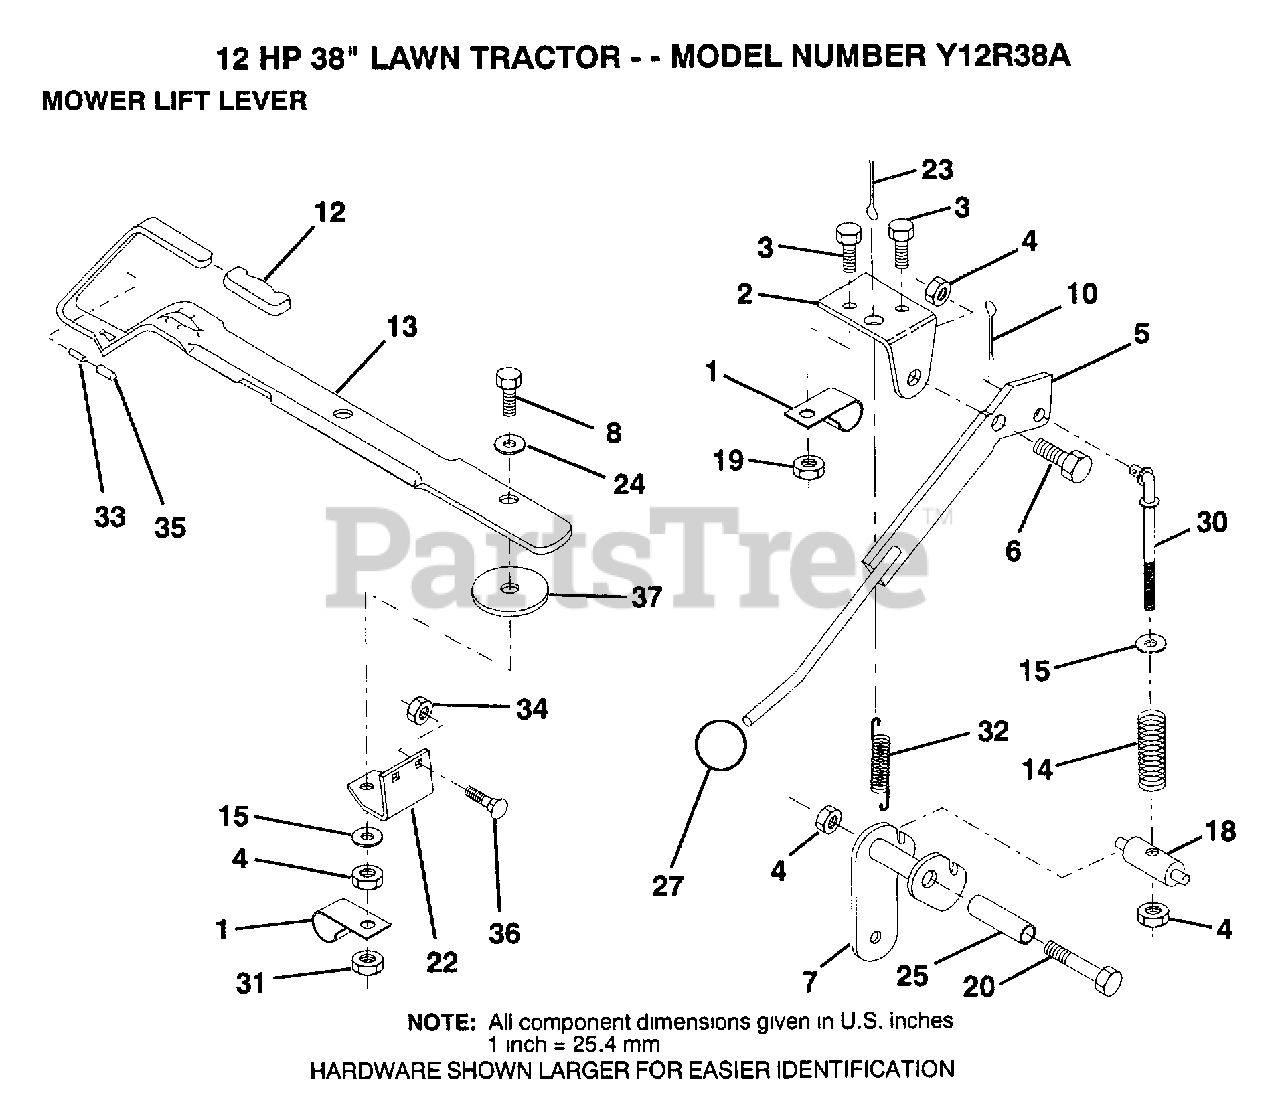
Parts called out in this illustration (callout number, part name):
1	"CLIP,INSULATOR"
2	BRKT CLUTCH
3	BOLT
5	CLUTCH LEVER AS
6	"BOLT, SHOULDER LT"
7	MWR CLUT ARM ASM
8	BOLT
10	COTTER PIN
12	LIFT LEVER HANDLE
13	LIFT HANDLE ASM
14	COMP CLUTCH SPRNG
15	WASHER HYT
18	TRUNNION
20	BOLT
22	LIFT LEVER BRKT
24	WASHER
25	TUBE SPACER
27	KNOB
30	ROD TENSION CLUTC
31	LOCKNUT
32	SPRING EXT
35	VINYL CAP RED
36	BOLT
37	WASHER T
